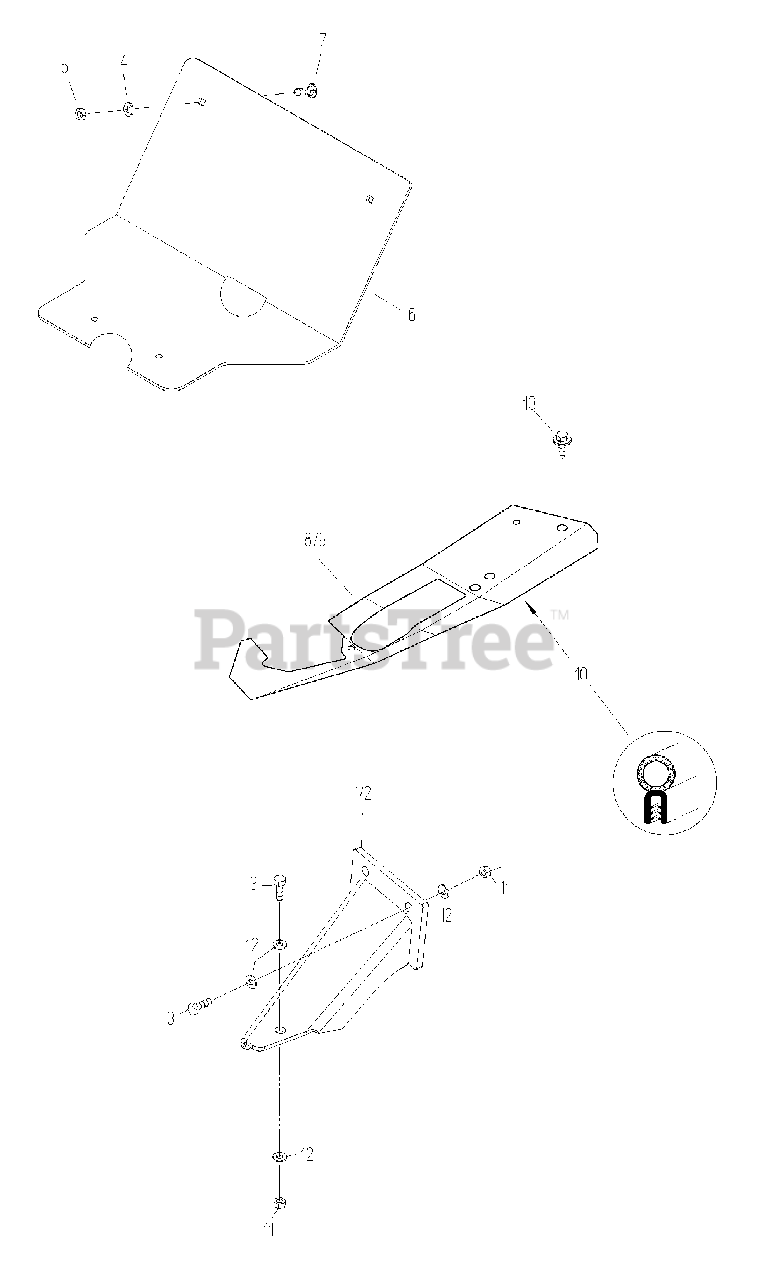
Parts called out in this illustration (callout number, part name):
1	CONSOLE, Front Left
2	CONSOLE, Front Right
6	CONSOLE, Rear
8	SHEET WIDENING, Left Bottom
9	SHEET WIDENING, Right Bottom
10	PROFILE SEALING, 4 ft. 4 in.
